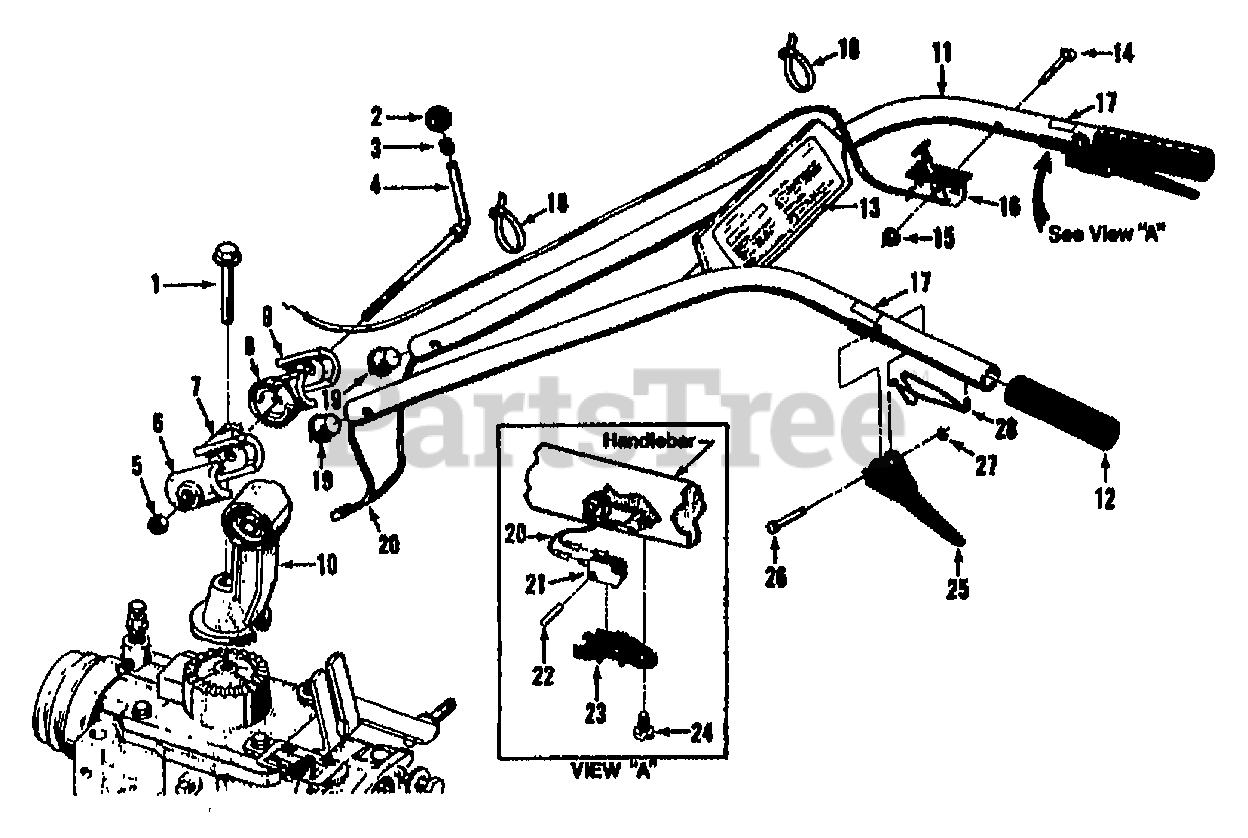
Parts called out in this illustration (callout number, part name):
1	BOLT 1/2-13X3.5 FH GR5
2	KNOB-CONTROL
3	RING-TOLERANCE .5325 ID
4	STUD-H/BAR W/NUT & RING (INCL. 2,3,5)
5	NUT-HEX JAM 1/2-13
6	CLAMP-LH HORSE 1021-1, HEIGHT ADJ.
7	RATCHET-H/BAR RED 2542-1, HEIGHT ADJ.
8	RATCHET-RH RED HORSE 2542-2, HEIGHT ADJ.
9	CLAMP-RH HORSE 1021-2, HEIGHT ADJ.
10	BASE-H/BAR RED 2534A, MOUNTING
11	HANDLEBARS - INCL. TWO EA. 12 & 17, ONE 13)
12	GRIP-H/BAR SMOOTH
13	DECAL-CONTROL PANEL OPC
14	BOLT-CH 1/4-20X2.00 ZP GR 5
15	NUT-HF/LK 1/4-20 ZP (WHIZ-LOCK)
16	CABLE-THROTTLE 7HP TEC. ENGINE ONLY
16	CABLE-THROTTLE 8HP KOHLER ENGINE ONLY
17	DECAL-FWD INTERLOCK
18	TIE-RED (PLASTIC)
19	RETAINER-HARNESS H/B OPC
20	HANDLEBAR HARNESS-WIRE OPC HORSE
21	SWITCH-H/B OPC - FORWARD INTERLOCK SYSTEM
22	PIN-LK .11X.58 HORSE OPC, HANDLEBAR SWITCH
23	HOUSING-SWITCH OPC, HANDLEBAR SWITCH
24	SCR-HW M10-24X.5 STH ZP
25	LEVER-HORSE OPC, FORWARD INTERLOCK
26	PIN-PIVOT OPC, FORWARD INTERLOCK LEVER
27	RING-KLIP 5304-25, FORWARD INTERLOCK
28	SPRING-H/B FORWARD INTERLOCK LEVER
